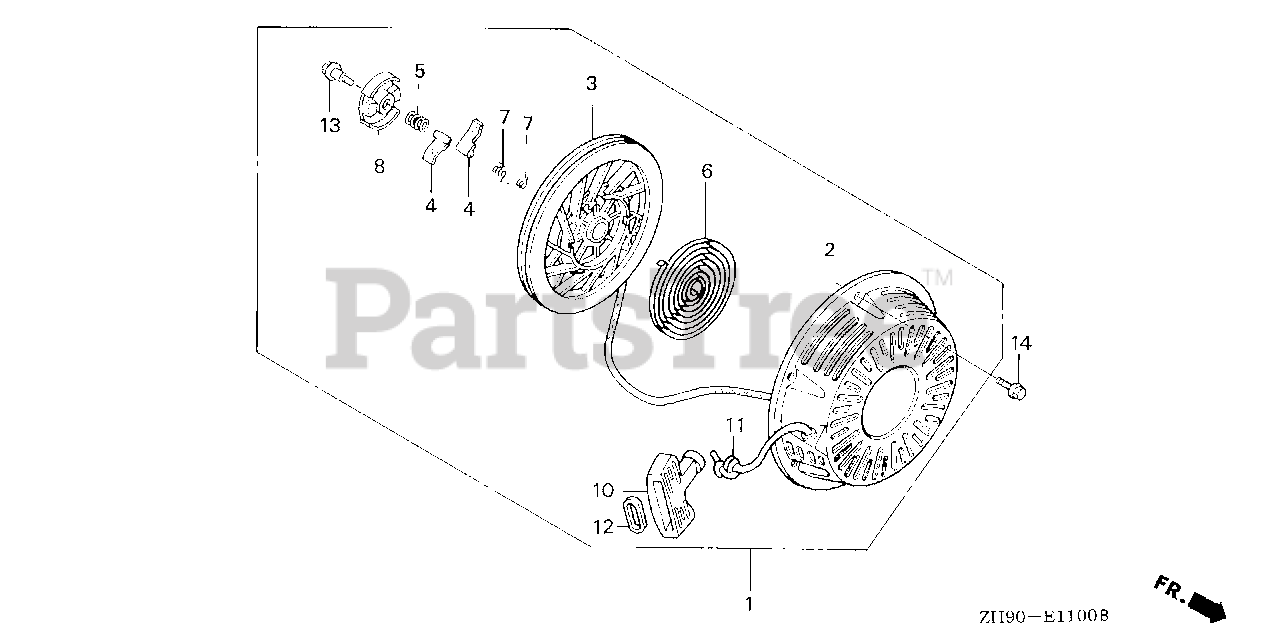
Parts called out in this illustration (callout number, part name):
1	STARTER ASSY., RECOIL *NH1* (BLACK)
1	STARTER ASSY., RECOIL *R280* (POWER RED)
2	CASE, RECOIL STARTER *R8* (BRIGHT RED)
2	CASE, RECOIL STARTER *NH1* (BLACK)
2	CASE, RECOIL STARTER *R280* (POWER RED)
3	PULLEY, RECOIL STARTER
4	RATCHET, STARTER
5	SPRING, FRICTION
6	SPRING, STARTER RETURN
7	SPRING, RATCHET
8	RETAINER, SPRING
10	GRIP, STARTER
11	ROPE, RECOIL STARTER
12	REINFORCEMENT, GRIP
13	SCREW, CENTER
14	BOLT, FLANGE (6X10)
